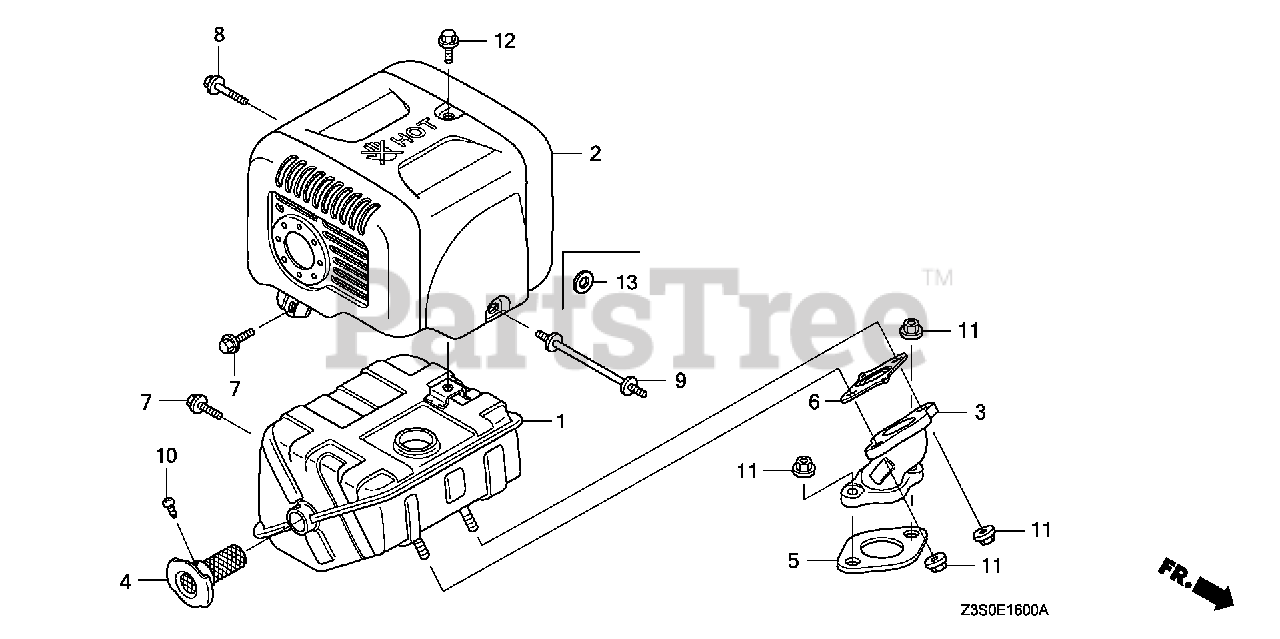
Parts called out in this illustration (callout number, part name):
2	PROTECTOR, MUFFLER
4	ARRESTER, SPARK
5	GASKET, MUFFLER
6	GASKET, MUFFLER (B)
7	BOLT, FLANGE (6X14)
8	BOLT, FLANGE (6X28) (CT200) Use up to Engine SN 1530314.
9	BOLT, STUD
10	SCREW, TAPPING (5X8)
11	NUT, FLANGE (8MM)
12	BOLT, FLANGE (6X8)
